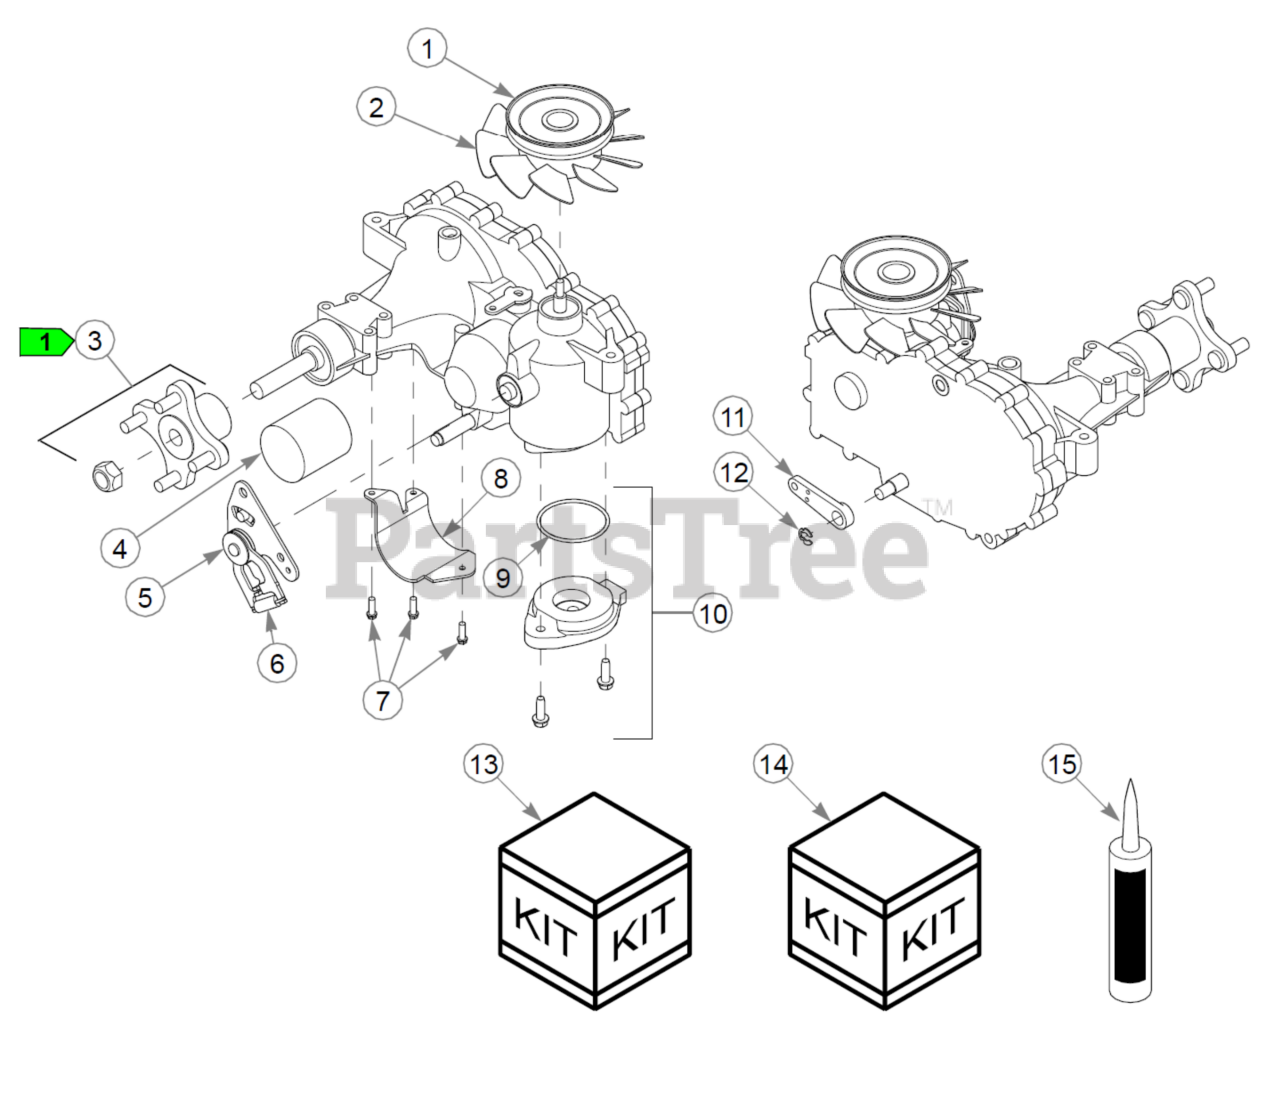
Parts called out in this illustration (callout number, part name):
1	FAN / PULLEY KIT
2	FAN - 7.0" (10 BLADE)
3	KIT, HUB, 4 BOLT
4	HYDRAULIC OIL FILTER
5	HG RTN CCW
6	HG RTN SPRING
7	CS .250-20 X .75 HX FLG
8	GUARD, TRANS FILTER
9	O-RING, ZT28/3100 CHARGE
10	COVER, ZT3100 CHRG PUMP
11	ZT2800 BRAKE ARM - 2007
12	CLIP, RETAINING
13	OIL RETENSION KIT
14	SEAL KIT
15	TUBE - SEALANT
